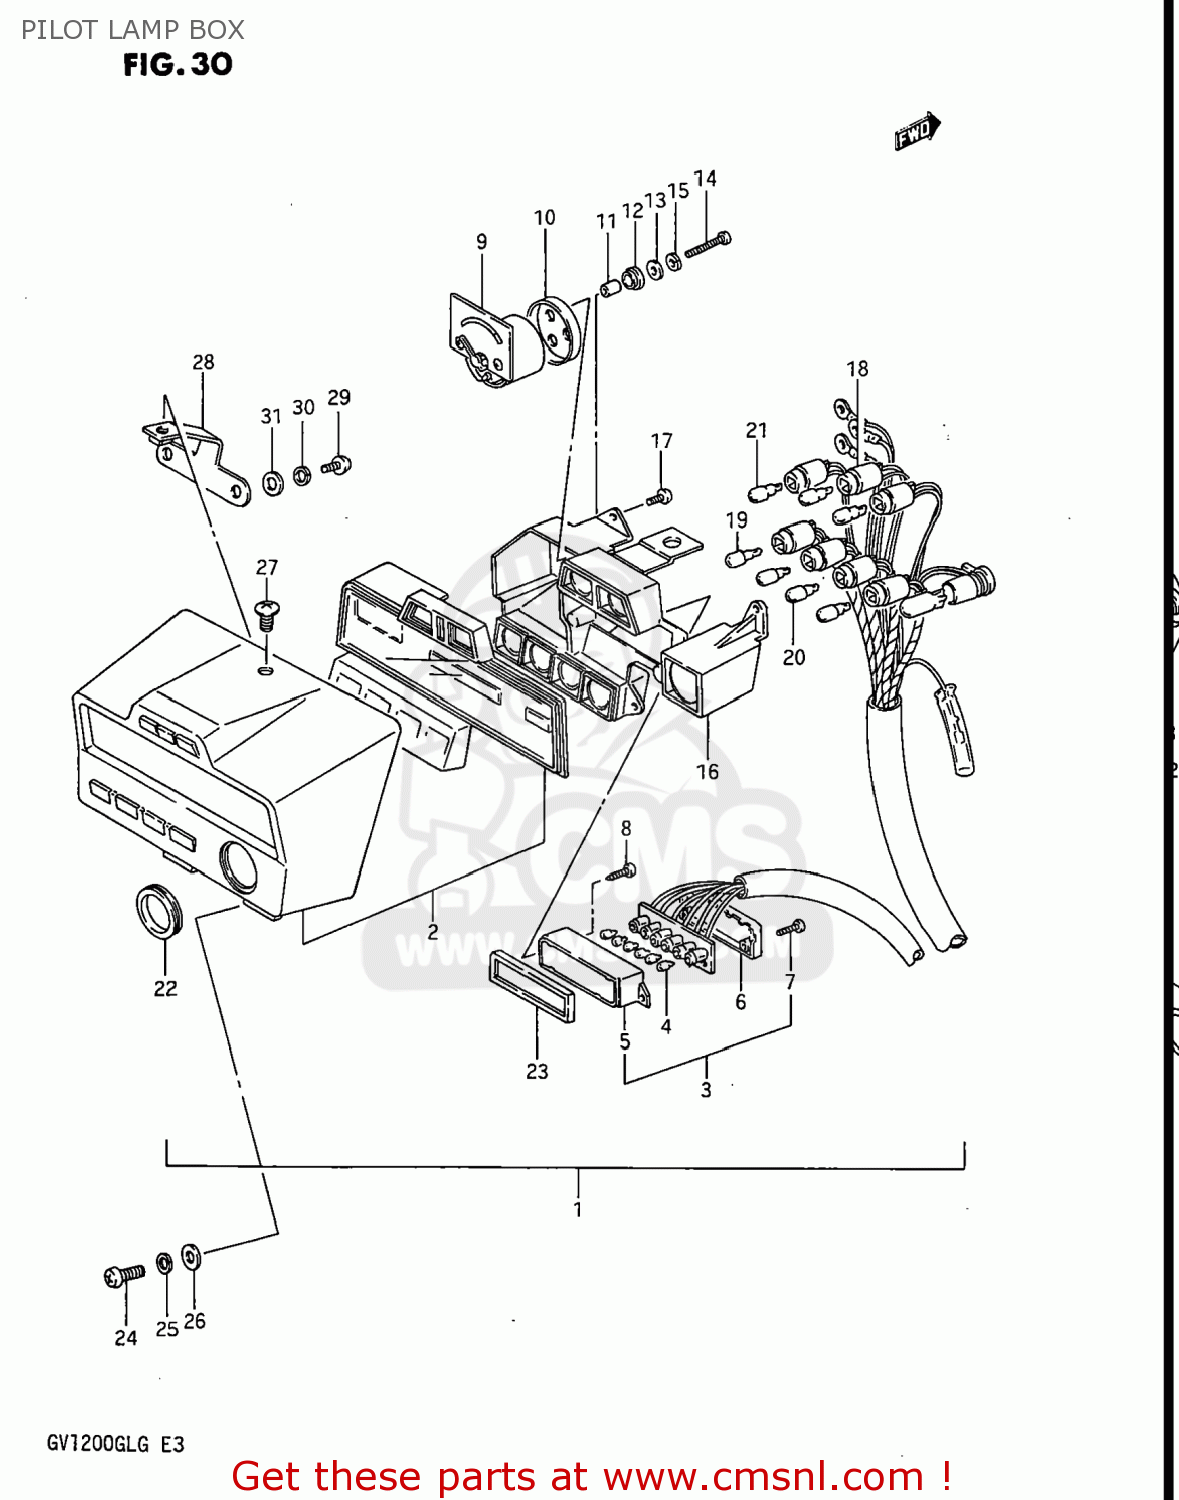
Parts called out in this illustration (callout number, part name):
1	BOX ASSEMBLY,PILOT LAMP
2	COVER SET,PILOT BOX
3	INDICATOR,GEAR POSITION
4	BULB(14V1.12W)
5	CASE,GEAR INDICATOR
6	COVER,LWR
7	SCREW,GEAR INDICATOR
8	SCREW,INDICATOR
9	METER,WATER TEMPERATURE
10	PAD
13	WASHER,FUEL METER
14	SCREW
15	LOCK WASHER
16	CASE,PILOT BOX,LOWER
17	SCREW
18	SOCKET,PILOT LAMP
19	BULB(12V3W,T6.5)
20	BULB(12V1.7W,T6.5)
21	BULB(12V3.4W,T10)
22	CUSHION
23	GASKET
24	SCREW
25	WASHER,LOCK
26	WASHER
27	SCREW 6X12
29	SCREW
30	WASHER,LOCK
31	WASHER,5MM
